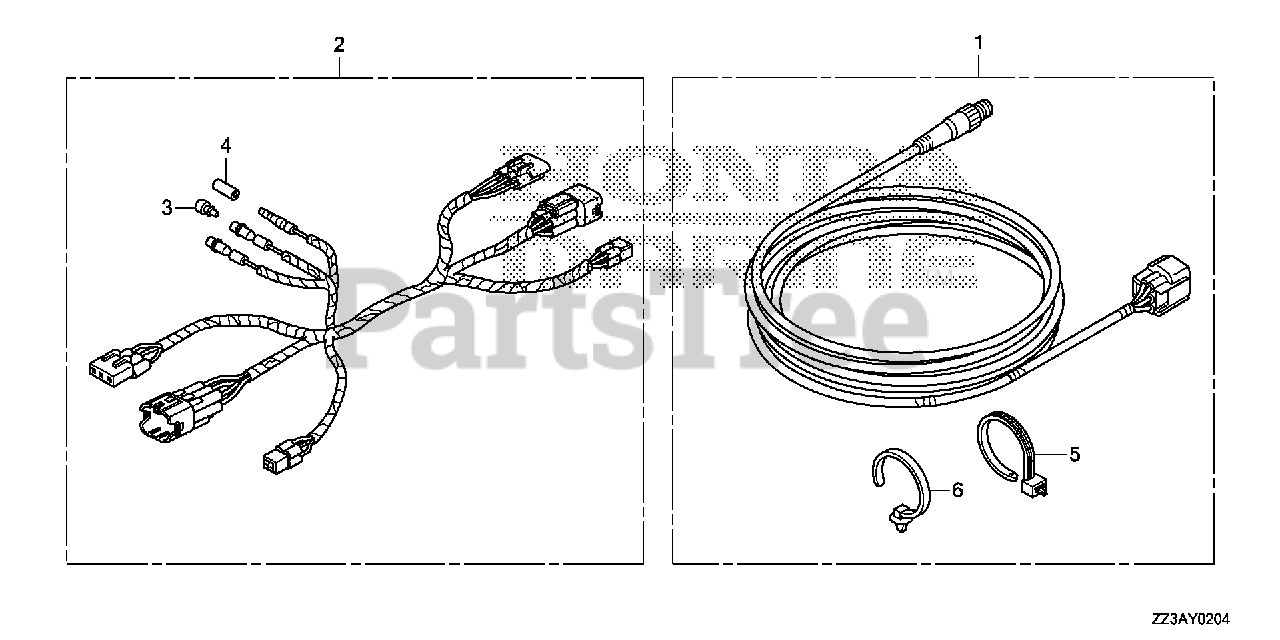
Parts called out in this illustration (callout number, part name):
1	KIT, CABLE (6FT) (NMEA)
2	HARNESS ASSY., REMOTE CONTROL SUB
3	PLUG, CONNECTOR (INNER)
4	PLUG, CONNECTOR (OUTER)
5	TIE, CABLE
6	CLIP, HARNESS BAND (155.3MM) (BLACK)
